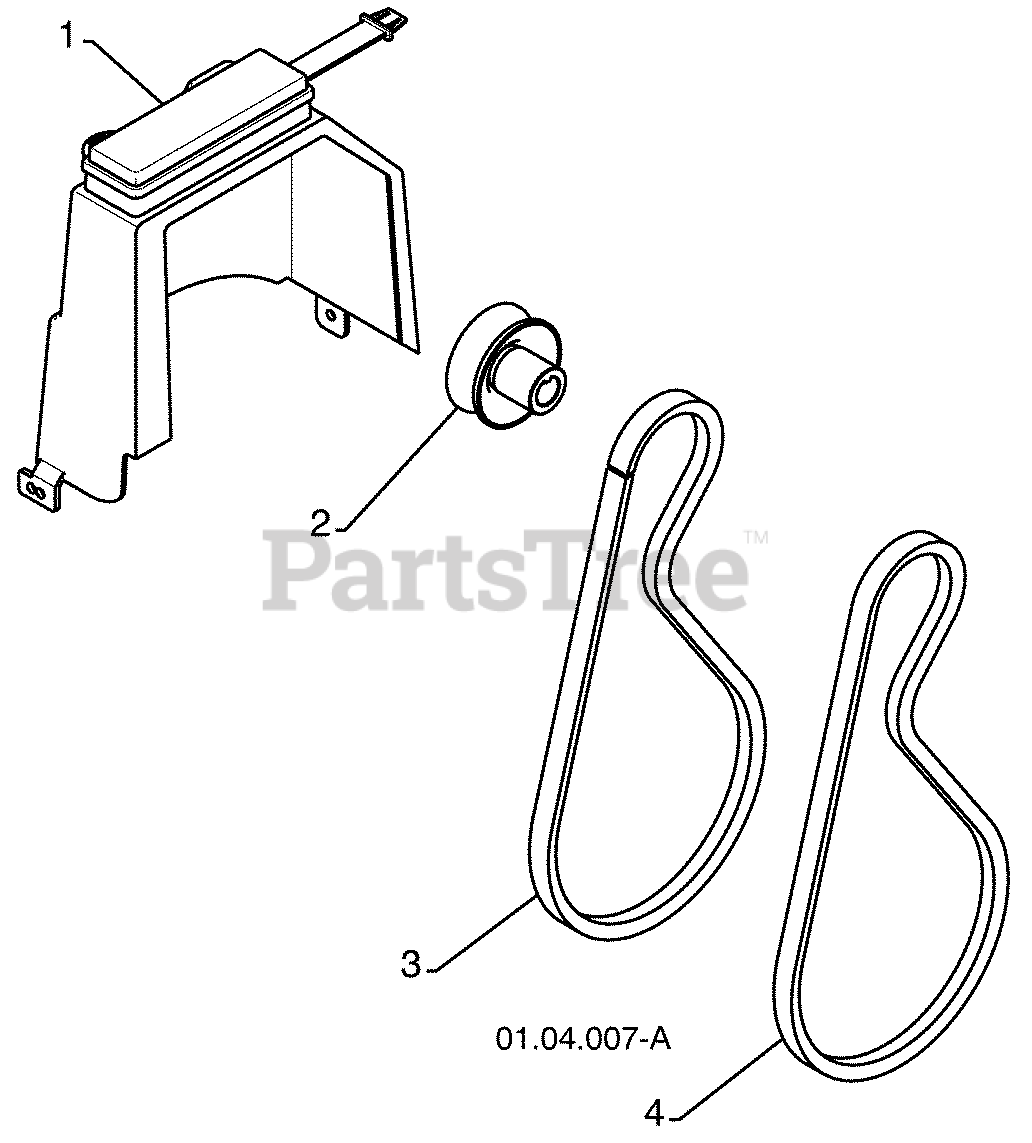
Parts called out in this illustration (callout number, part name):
1	COVER ASSEMBLY
2	PULLEY
3	TRACTION BELT
4	IMPELLER BELT
